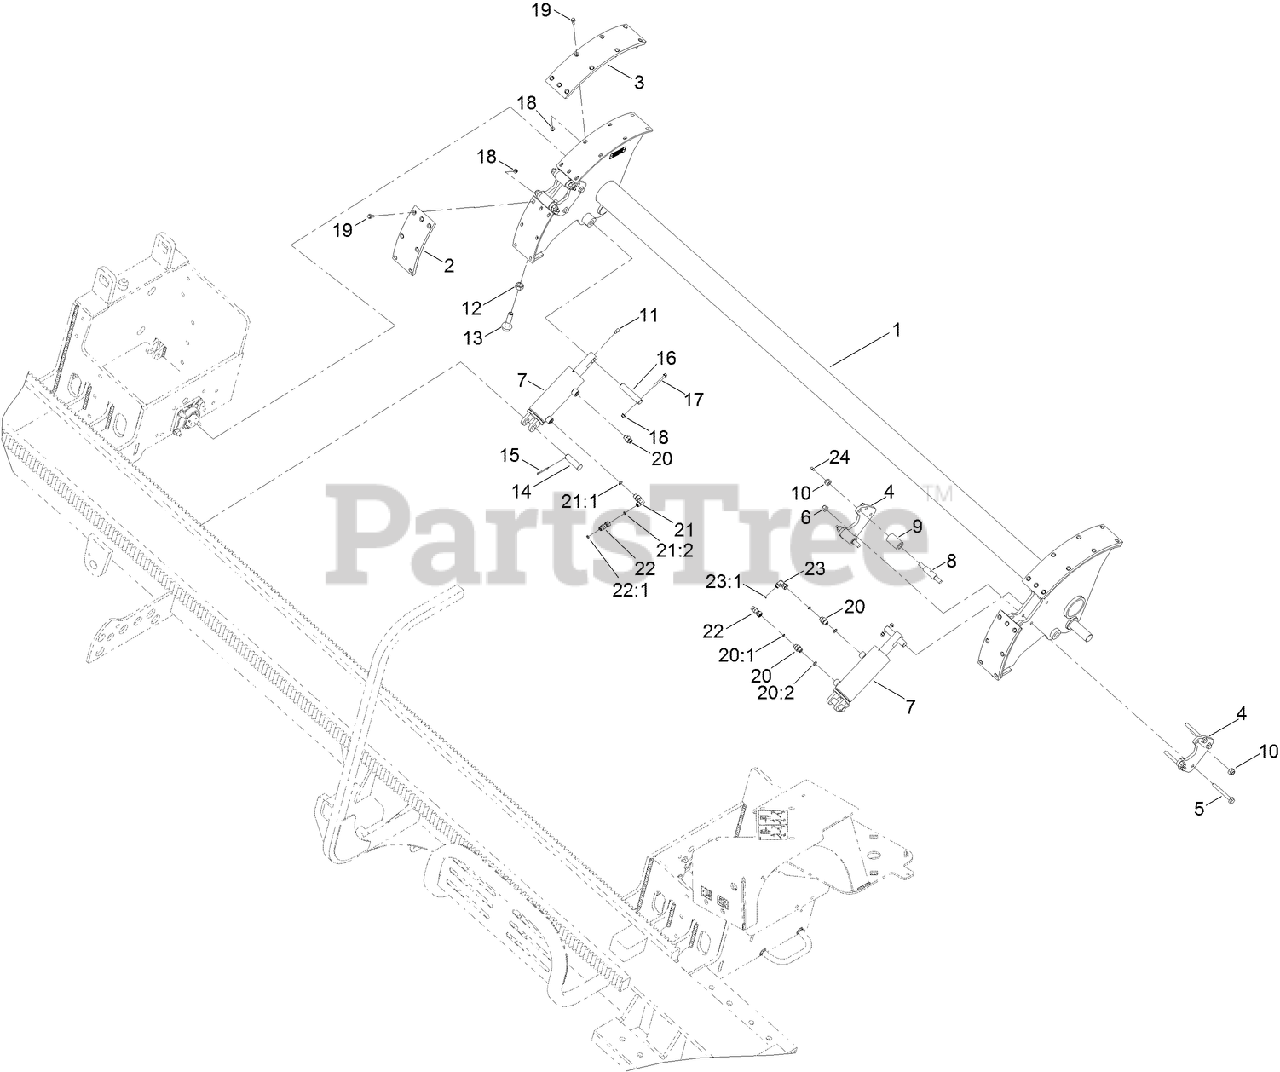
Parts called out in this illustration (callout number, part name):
1	ROD LOADER CAM
2	PAD-WEAR, ROD LOADER (SHORT)
3	PAD-WEAR, ROD LOADER (LONG)
4	PLATE-HOLDER, PIPE
5	SCREW-HHF
6	NUT-LOCK, NI
7	HYD CYLINDER ASM
8	SHAFT-ROLLER, PIPE
9	TUBE-ROLLER
10	NUT-HEX
11	FITTING-GREASE, 90 DEG
12	NUT-HEX
13	SCREW-HHF
14	PIN-CLEVIS
15	PIN-COTTER
16	PIN-STRAIGHT
17	SCREW-HHF
18	NUT-FLANGE, NI
19	SCREW-HHF
20	FITTING-STRAIGHT
20:1	O-RING
20:2	O-RING
21	FITTING-ELBOW 90
21:1	O-RING
21:2	O-RING
22	FITTING-STRAIGHT
22:1	O-RING
23	FITTING-ADAPTOR
23:1	O-RING
24	FITTING-GREASE
